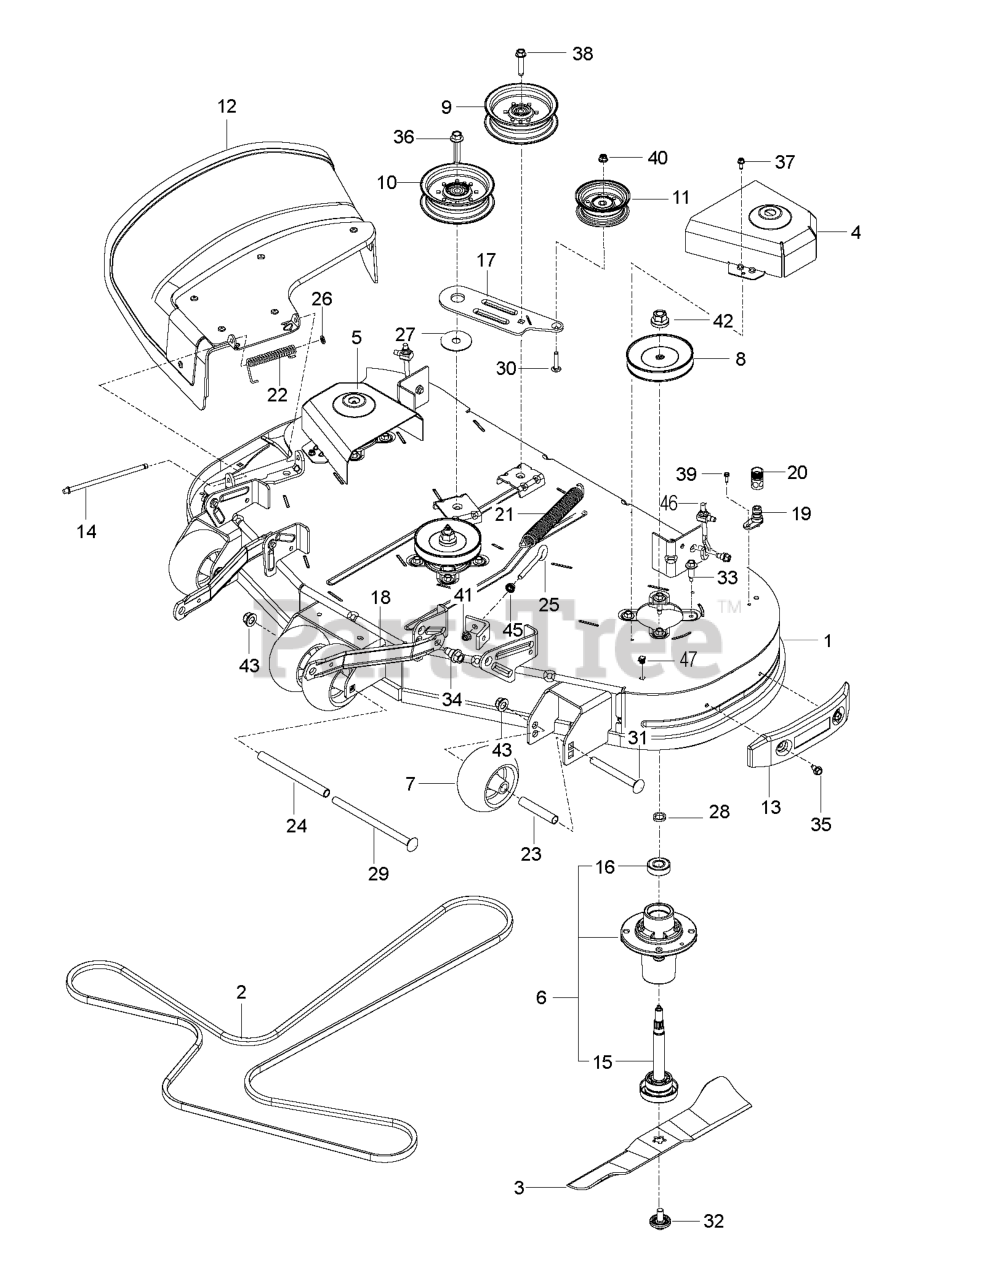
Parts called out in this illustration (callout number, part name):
1	Decals
2	BELT.DRIVE
3	BLADE.BAGGER.COM.CLRCT.48".BLK
3	BLADE.BAGGER.RES.CLRCT.48".BLK
4	COVER.PNT.MANDREL.LH.ZTR.GREY
5	COVER.PNT.MANDREL.RH.GREY
6	MANDREL ASM, CAST IRON
6	MANDREL.DECK.ASSEMBLY
7	ROLLER, GAUGE .635 BORN
8	MANDREL.PULLEY.38.BRIGHT.ZINC
8	Pulleys
9	PULLEY.IDLER.2006
10	PULLEY.IDLER.MWR.STATI.LH
11	PULLEY.IDLER.48"PRIMARY
12	GSPW Deflectors
13	BUMPER.ASM.SIDE.TRIM.CLRCUT.48
15	SHAFT ASM MANDREL
16	BEARING
16	Spacers
17	ARM.PNT.CLUTCHING.EDIP
17	ARM.PNT.CLUTCHING.ASM.EDIP
18	ARM.RFIXED.MOWER.SUSPNSIONX431
18	ARM.SUSPENSION.MOWER
19	PORT.WASHOUT
20	COUPLING.QUICK CONNECT
21	SPRING.EXTENSION
22	SPRING.42.FCS.DEFLECTOR
23	Tubes
23	TUBE, ROLLER AXLE LONG
24	TUBE, ROLLER AXLE
24	Tubes
25	GSPW Bolts
26	NUT PUSH M
28	WASHER.SPACER.MANDREL
29	RHSNB 1/2-13 X 8 GR5 ZD
29	Bolts
32	BOLT.WASHER.ASM.7/16-2
32	BLADE BOLT/WASHER
33	BOLT.HEX.WASHR.HED.313-18X1.19
34	BOLT.SHOULDER
35	BOLT.5/16HEX.WHS.HD
36	SCREW.7/16-14 X 2.125.WASHER
37	SCREW.1/4-20X5/8
38	BOLT;HEX_3/8-16 X 1.78.CLRZINC
39	Screws
39	SCREW
40	NUT LOCK FLG 3/8-16 UNC
41	NUT HEXAGON FLANGE 5/16-18 ST
42	NUT.FLANGE.LOCK.TOP
42	Nuts
43	NUT 1/2-13 HEX FLANGE NYLOK CL
45	GSPW Hardware
46	LINK.ASM.ADJUSTABLE
46	TRUNNION
46	NUT.HEX.FLANGE.INS.BLK.3/8-16
47	Plugs
65	NUT NUT.3/8-16.HEX.JAM.Z 3/8-1
